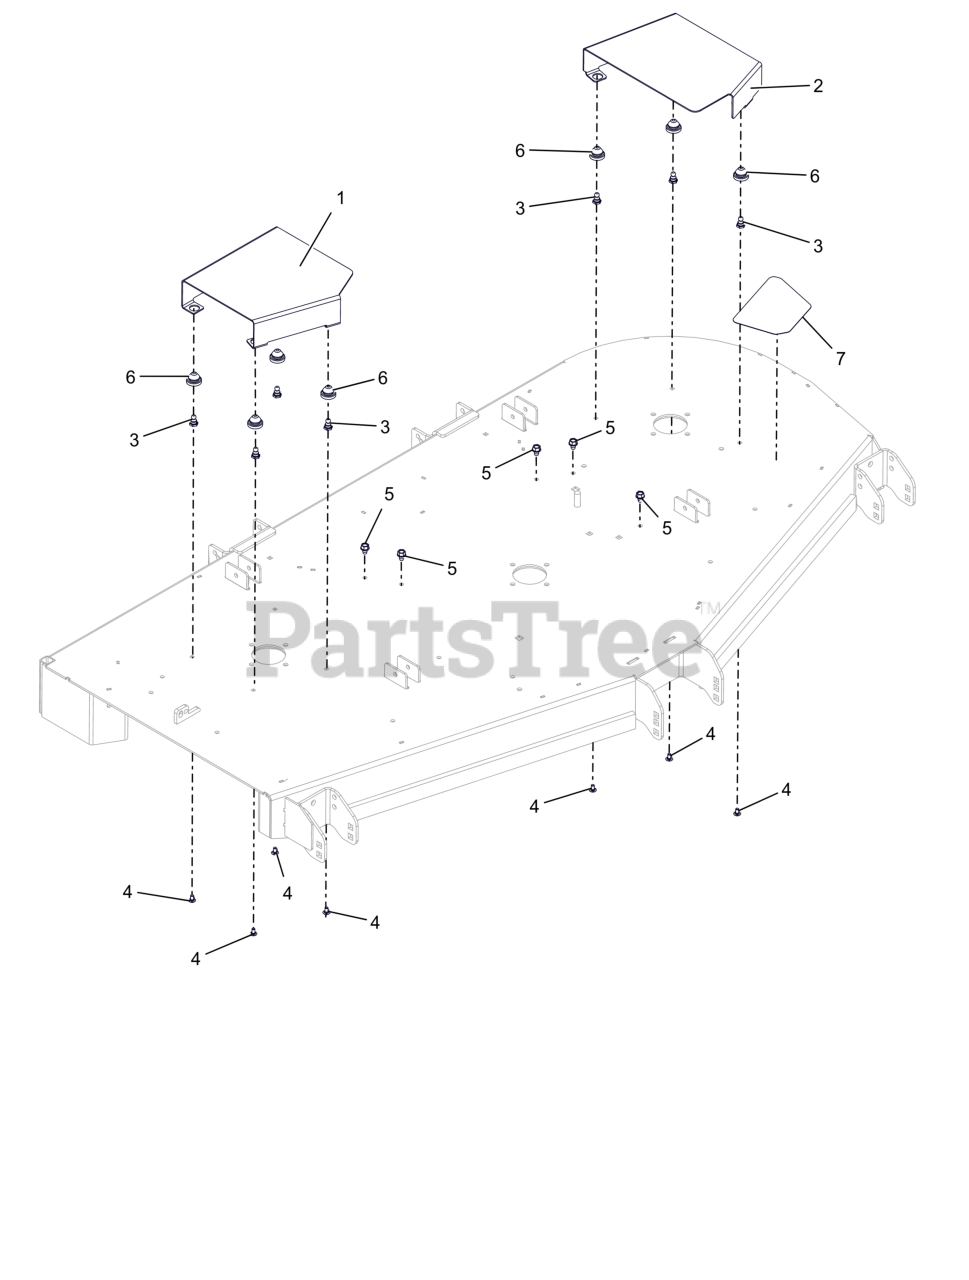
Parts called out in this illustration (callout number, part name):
1	GUARD, 72" DECK RH SPINDLE PULLEY
2	GUARD, 72" DECK LH SPINDLE PULLEY (RED)
3	STUD, BALL FEMALE .250-20 THREAD
4	BLT, RHSSN.25-20X.500 G5 ZCC
5	SCR,TAP .375-16X.50 HWH TR ZCC
6	COUPLING, RUBBER PUSH-IN
7	GRIP, STEP ANTI SKID
